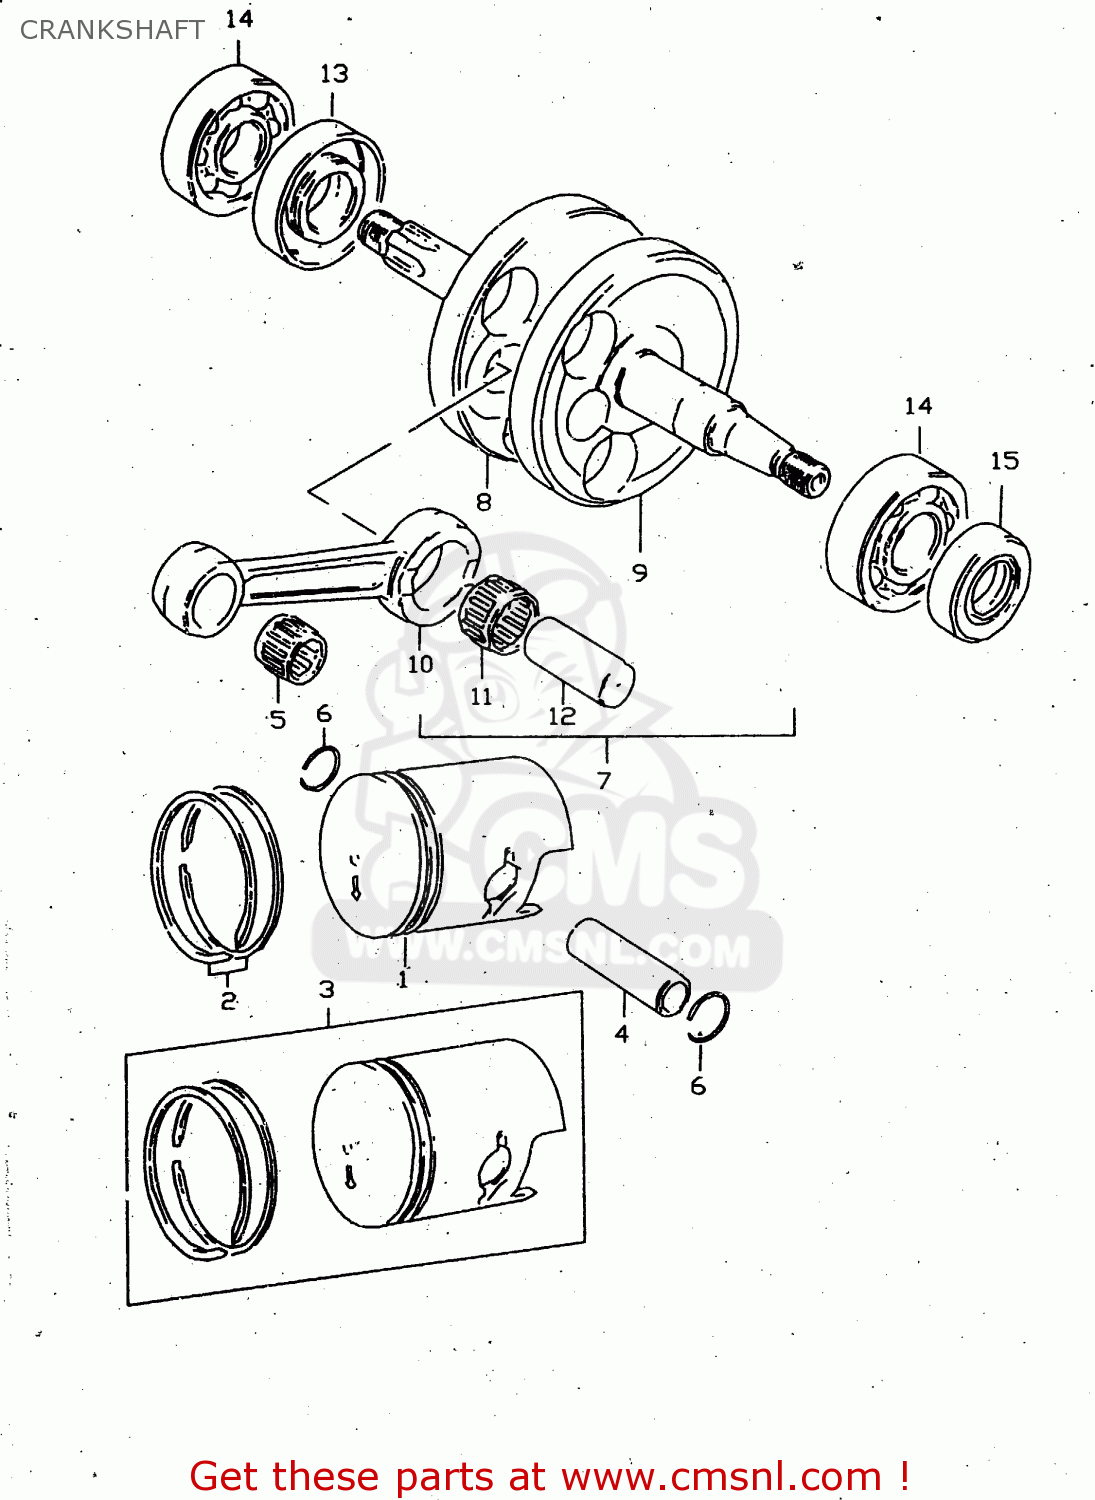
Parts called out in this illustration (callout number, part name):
1	PISTON
2	RING SET,PISTON
3	PISTON SET (OS:0.5)
4	PIN,PISTON
5	BEARING(12X16X16)
6	RING,SNAP
7	CRANKSHAFT ASSY
8	CRANKSHAFT,R
9	CRANKSHAFT,L
10	ROD,CONNECTING
11	BEARING(15X21X9.8)
12	PIN,CRANK
13	SEAL,OIL(22X40X8)
14	BEARING(17X40X12)
15	OIL SEAL (17X29X7)
